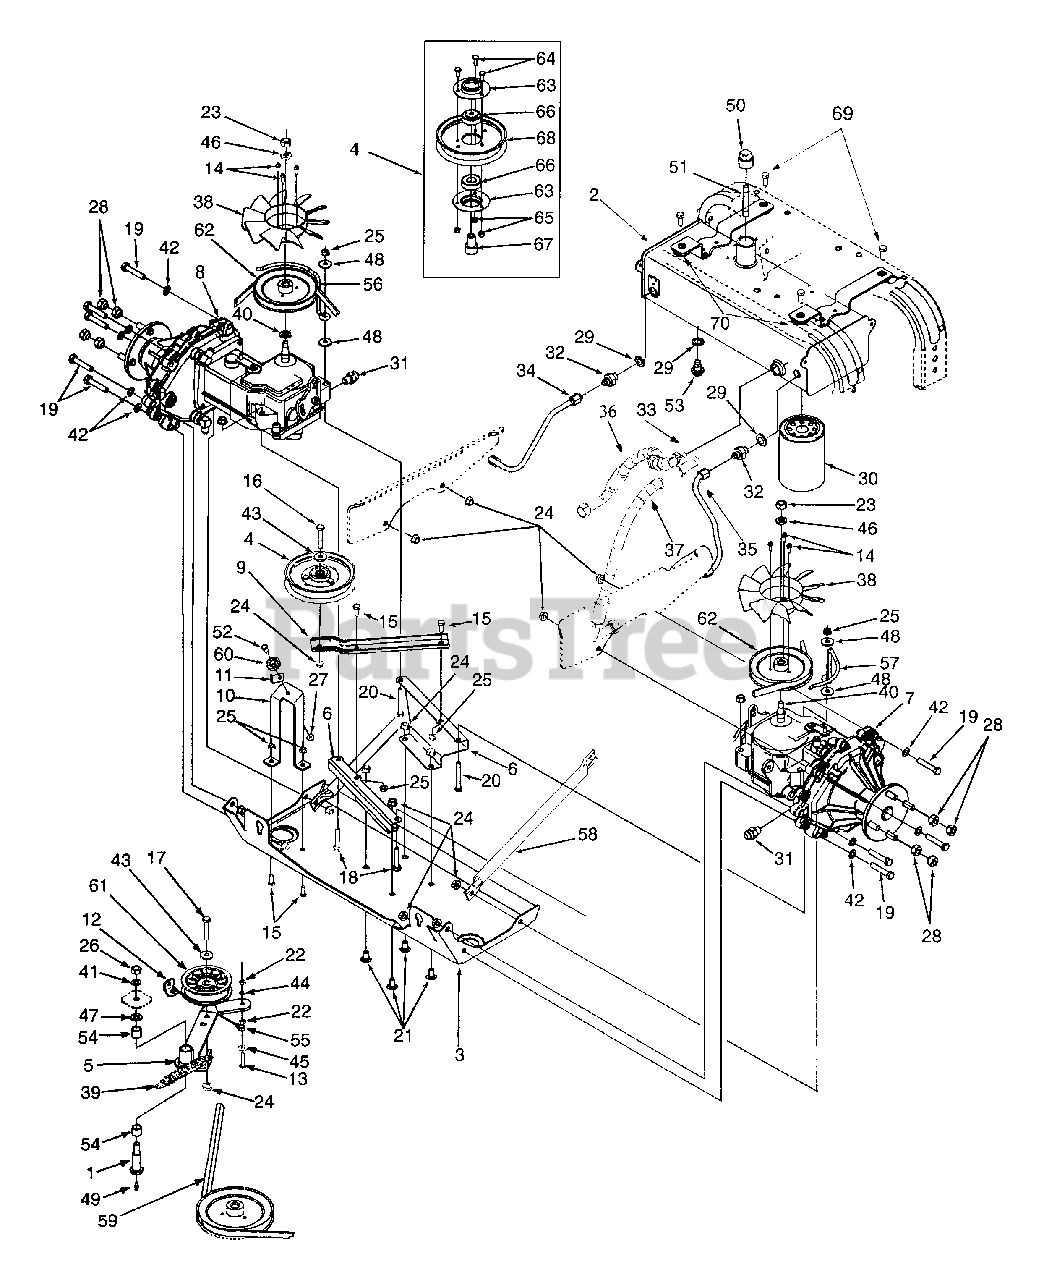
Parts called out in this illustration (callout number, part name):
1	Shoulder Bolt, Special
2	Tank Ass'y, Hydraulic
3	Plate Ass'y, Skid
4	Pulley Ass'y, Idler 5.0 in.
8	Transmission Ass'y LH
11	Bracket, Cable Retainer
12	Bracket, Cable Mtg.
13	Screw, Hex Cap 1/4-28 x 1.25 GR5
14	Screw, Hex Wash. Hd. Tapp #12-24 x .62
15	Screw, Hex Cap 5/16-18 x .75 GR5
16	Screw, Hex Cap 3/8-16 x 2-1/4 GR5
17	Screw, Hex Cap 3/8-16 x 1-3/4 GR5
18	Screw, Hex Cap 5/16-18 x 2.0 GR5
19	Screw, Hex Cap 3/8-16 x 2.0 GR5
20	Screw, Hex Cap 5/16-18 x 2.50 GR5
21	Bolt, Carriage, 3/8-16 x .75
22	Nut, Hex, 1/4-28
23	Nut, Hex, 1/2-20
24	Nut, Hex Flange Lock, 3/8-16
25	Nut, Hex Flange Lock, 5/16-18 GR5
26	Nut, Hex, 7/16-14
27	Nut, Hex Lock, 1/4-20
28	Nut, Lug, 7/16-14
29	Seal, Drain Plug
30	Filter Element, Oil
31	Fitting, Connector, 1/2 x 3/8
32	Fitting, Connector
33	Fitting, Tee, 1/2 x 1/2 x 3/4
34	Tube, Inlet LH
35	Tube, Inlet RH
36	Hose, Outlet LH
37	Hose, Outlet RH
38	Fan, 10 Blade
39	Spring, Extension
41	Washer, Lock, 7/16
42	Washer, Flat, .406 x .75 x .06
43	Washer, Flat, .385 x 1.0 x .135
44	Washer, Lock, 1/4 ID
45	Washer, Flat, .283 x .75 x .030
46	Washer, Lock, 1/2
47	Washer, Flat, .469 x .875 x .105
48	Washer, Flat, 5/16 x .934 x .100
49	Fitting, Grease
50	Plug, Pipe, w/Vent 3/4 NPTF
51	Tube, Dipstick
52	Bolt, Shoulder, 1/4-28: .375
53	Plug, Oil Drain
54	Bearing, Sleeve, .628 x .75 x .625
55	Cable, Declutching
56	Rod, Belt Retaining RH
57	Rod, Belt Retaining LH
59	V-Belt, Transmission Drive A-Section x 54.24 Lg
60	Cable Roller
61	Pulley, Flat Idler 3.5 in.
62	Pulley, Transmission
63	Cup, Bearing
64	Screw, Hex Cap, 1/4-20 x .62 GR5
65	Nut, Hex Insert Lock, 1/4-20
66	Bearing, Ball
67	Spacer, Idler
68	Pulley, Idler 5.0 in.
69	Hex Head / Wsh 3/8-16 x .625
70	Retainer Nut 3/8-16
